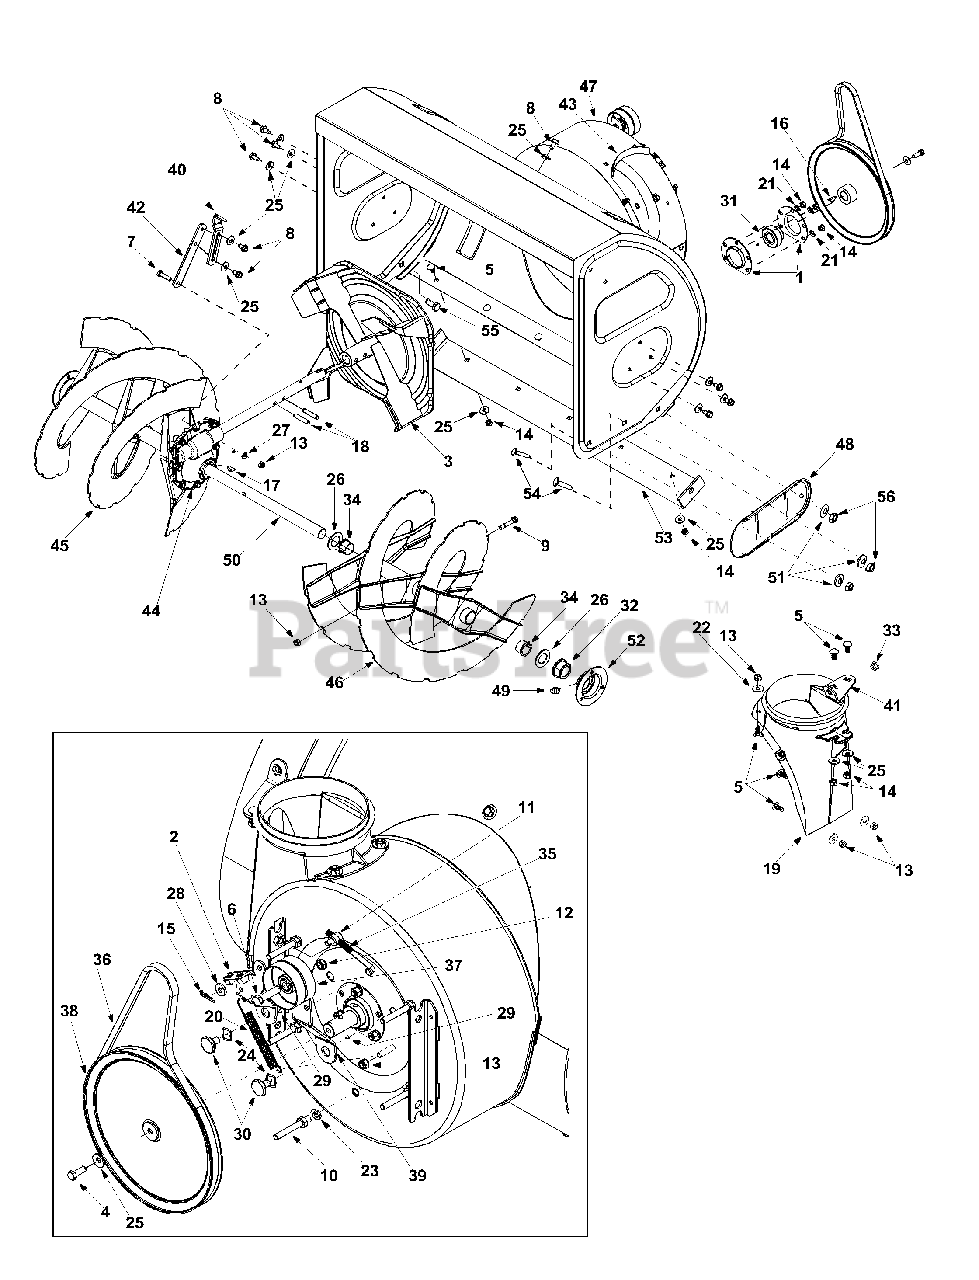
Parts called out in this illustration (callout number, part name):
1	Bearing Housing
2	Bracket Assembly: Auger Break
5	Carriage Bolt 5/16-18 x .750"
6	Hex Screw, Special 3/8-24 x 1.5"
7	Hex Screw 5/16-18 x 1.25"
8	Self-Tapp. Screw 5/16-18 x .625"
9	Shear Bolt 5/16-18 x 1.75"
11	Ferrule
12	Jam Nut 3/8-24
13	Hex Lock Nut 5/16-18
14	Hex Nut 5/16-18
15	Hairpin Clip
18	Spiral Pin
19	Chute Adapter
20	Extension Spring
21	Lock Washer
22	5/16 Washer
23	Lock Washer
24	Wave Washer
25	Beleville Washer
26	Flat Washer
27	Spring Washer
28	Flat Washer
30	Shoulder Screw
31	Self-Aligning Bearing
32	Flange Bearing w/ Flats
33	Plastic Bushing
34	Flange Bushing
35	Idler Rod: Auger
36	V-Belt
37	Flat Idler
38	Pulley
49	Lube Fitting
50	Spiral Axle
51	Bell Washer
54	Carriage Screw
55	Carriage Bolt
56	Hex Nut 3/8-16
